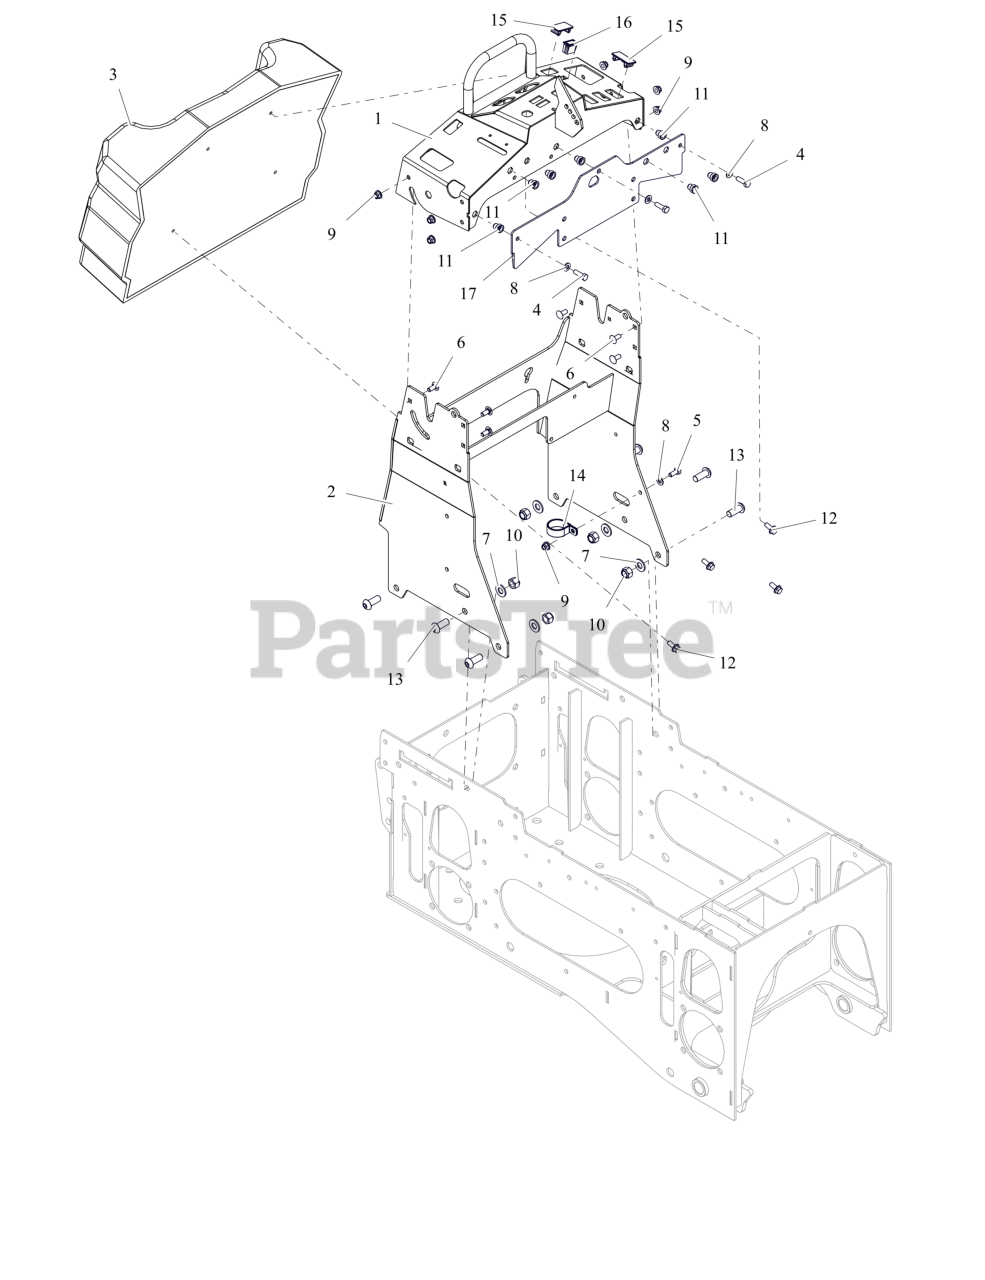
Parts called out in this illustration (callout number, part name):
1	WLDMT, CONSOLE TOP - W/DECALS
2	WLDMT, CONTROL TOWER W/DECAL
3	PAD- MAMMOTH OPERATOR
4	BLT,HEX .31-18X1.00 G5 ZCC
5	BLT,HEX .31-18X.75 G5 ZCC
6	BLT, RHSSN.31-18X.750 G5 ZCC
7	WSHR,FLT .531X1.062X.095 ZCC
8	WSHR,FLT .344X.688X.065 ZCC
9	NUT,LK-NYL-FLG .31-18 G5ZC120
10	NUT,NYL .50-13 G5 ZCC
11	RVT, HEX 5/16-18 SHORT
12	BLT- SERHFWH .312-18X.75 ZCC
13	BOLT- BUTTON HEAD 1/2-13X1.25
14	CLAMP- CUSHIONED 1-3/8 X 11/32
15	PLUG,DASH PANEL
16	SWITCH,BLANK
17	PLATE- CONTROL ACCESS PANEL
